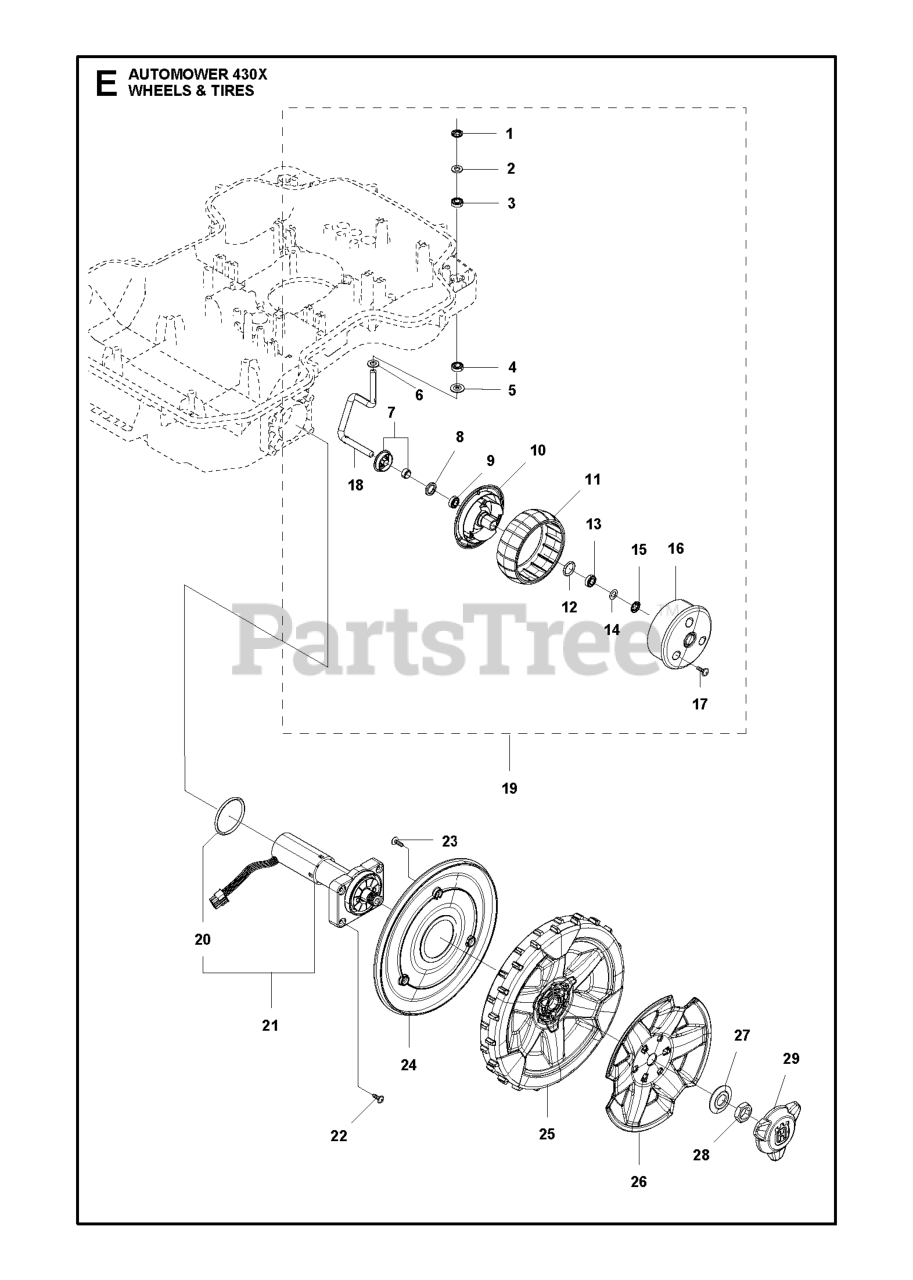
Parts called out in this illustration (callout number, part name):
2	MUFFLER.LT.BRIGGS.14HP.IC/OHV
9	KEEPER.BELT.ENGINE.3.25 (3 2)
12	PULLEY ENGINE
15	RP TANK FUEL FRT 1.5 GAL
18	FUEL CAP
20	CONTROL.TH/CK.COBRA.KO
21	SCREW
28	LINE.FUEL.20"FRONT.EMI
29	KIT.SPARK ARRESTOR 794945 B&S
37	HOSE CLAMP
42	LOCKWASHER
43	BOLT HEX 7/16-20X4-1/4"
69	REPL BY 532 27 22-93
79	SCREW.SOCKET HD.5/16-1
81	TUBE, DRAIN OIL ASM.
82	PLUG DRAIN OIL EASY
84	SCREW.3/8-16
85	NUT
90	SCREW 3/8-16X1
